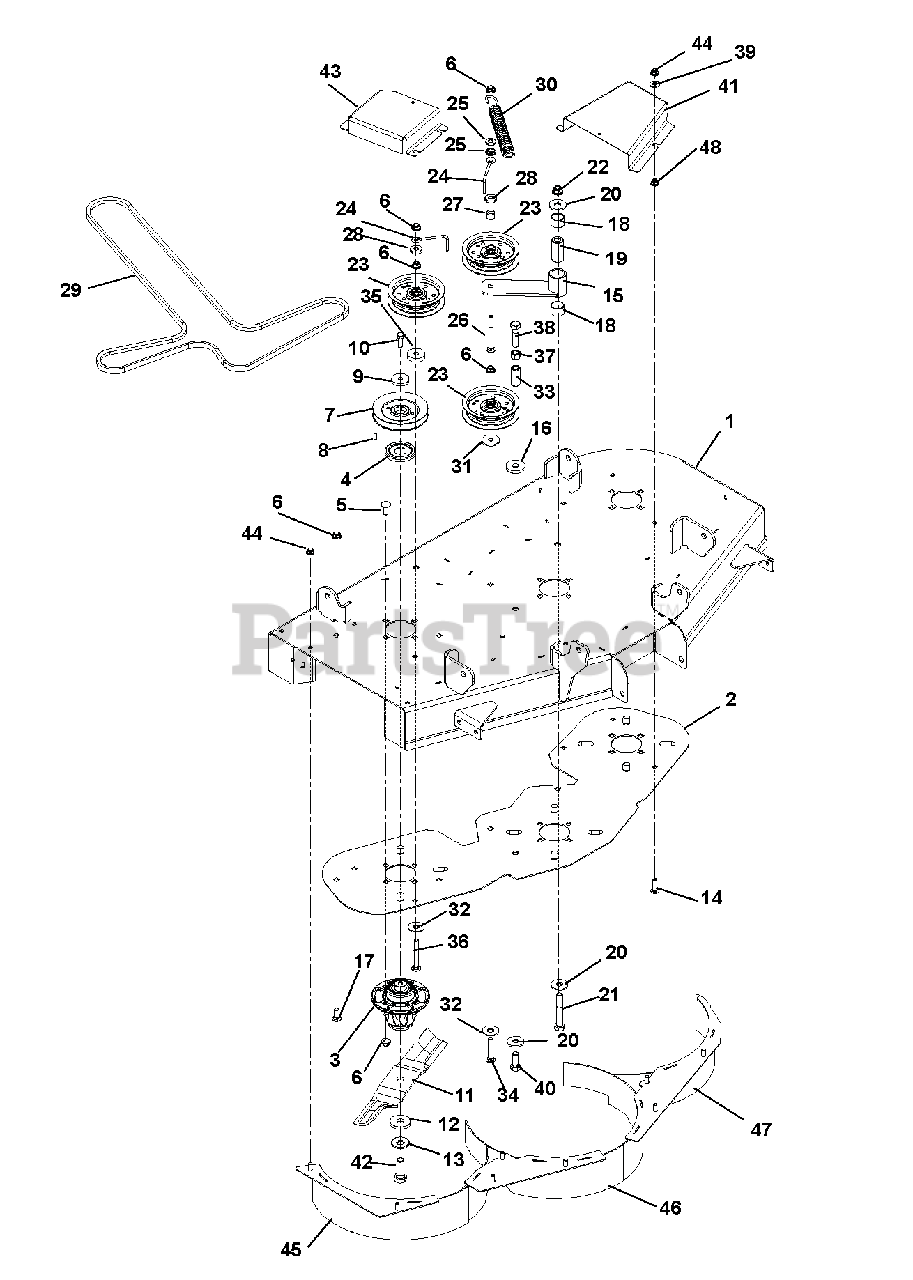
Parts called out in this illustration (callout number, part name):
1	XL-42 DECK KIT WITH DECALS
2	DOUBLER PLATE, 42 XL
3	SPINDLE ASSEMBLY
4	DUST CAP
5	@BLT-RDHDSQNK .38-16X1.25 G5YZ
5	@BLT-RDHDSQNK .38-16X1.50 G5YZ
6	@NUT-LK-NYL-FLG .38-16 YWZC
7	PULLEY, SPINDLE
8	KEY, SQ .25 X .38 X .25
9	WSHR,FLT STL.406X1.50X.245YWZC
10	BLT-HEX .38-16X1.0 GR8 YZ EP30
11	BLADE, MULCH 14.50"
12	WSHR-FLT .640X1.75X.250
13	WSHR-BLVL .669X1.535X.138
14	BLT-SERHFWH .312-18X.50 YWZC
15	WELDMENT, IDLER ARM
16	WSHR-FL-STL .515X1.625X.250 YZ
17	@BLT-RDHDSQNK .38-16X1.00 G5YZ
18	BRG, 1.00 X 1.12 X .75
19	BSHG, SPCR .502X.997X2.03 PM
20	WSHR-FL-STL.511X1.441X.125 YWZ
21	@BLT-HEX .50-13X3.25 GR5 YWZC
22	@NUT-LK-NYL-FLG .50-13 YWZC
23	ASM, IDLER 4"
24	BELT FINGER
25	BSHG-FLG .406X.88X.270X.140
26	@BLT-RDHDSQNK .38-16X3.50 G5YZ
27	BSHG-SLV .391X.688X.52 PM
28	WSHR-FL-STL .406X1.00X.188 YWZ
29	V-BELT, HA-WRAPPED
30	EXTENSION SPRING
31	WSHR-FL-STL .390X1.5X.125 YWZC
32	PLATE,IDLER MNT REINFORCEMENT
33	NUT, COUPLING 1/2-13X1.75 YWZC
34	@BLT-RDHDSQNK .38-16X2.25 G5YZ
35	SPACER, .39 X 1.50 X .380
36	@BLT-RDHDSQNK .38-16X3.00 G5YZ
37	@NUT-HEX .50-13 YWZC
38	@BLT-HEX .50-13X2.00 GR5 YWZC
39	NUT-PUSH .312
40	@BLT-HEX .50-13X1.25 GR5 YWZC
41	BELT COVER, LEFT
42	BLT-HEX .62-18X1.75 GR8 YWZC
43	BELT COVER, RIGHT
44	@NUT-LK-NYL-FLG .31-18 YWZC
45	WMT, 42 MULCH BAFFLE (RH)
46	WMT, 42 MULCH BAFFLE (CTR)
47	WMT, 42 MULCH BAFFLE (LH)
48	NUT- JAM .312-18 YWZC
